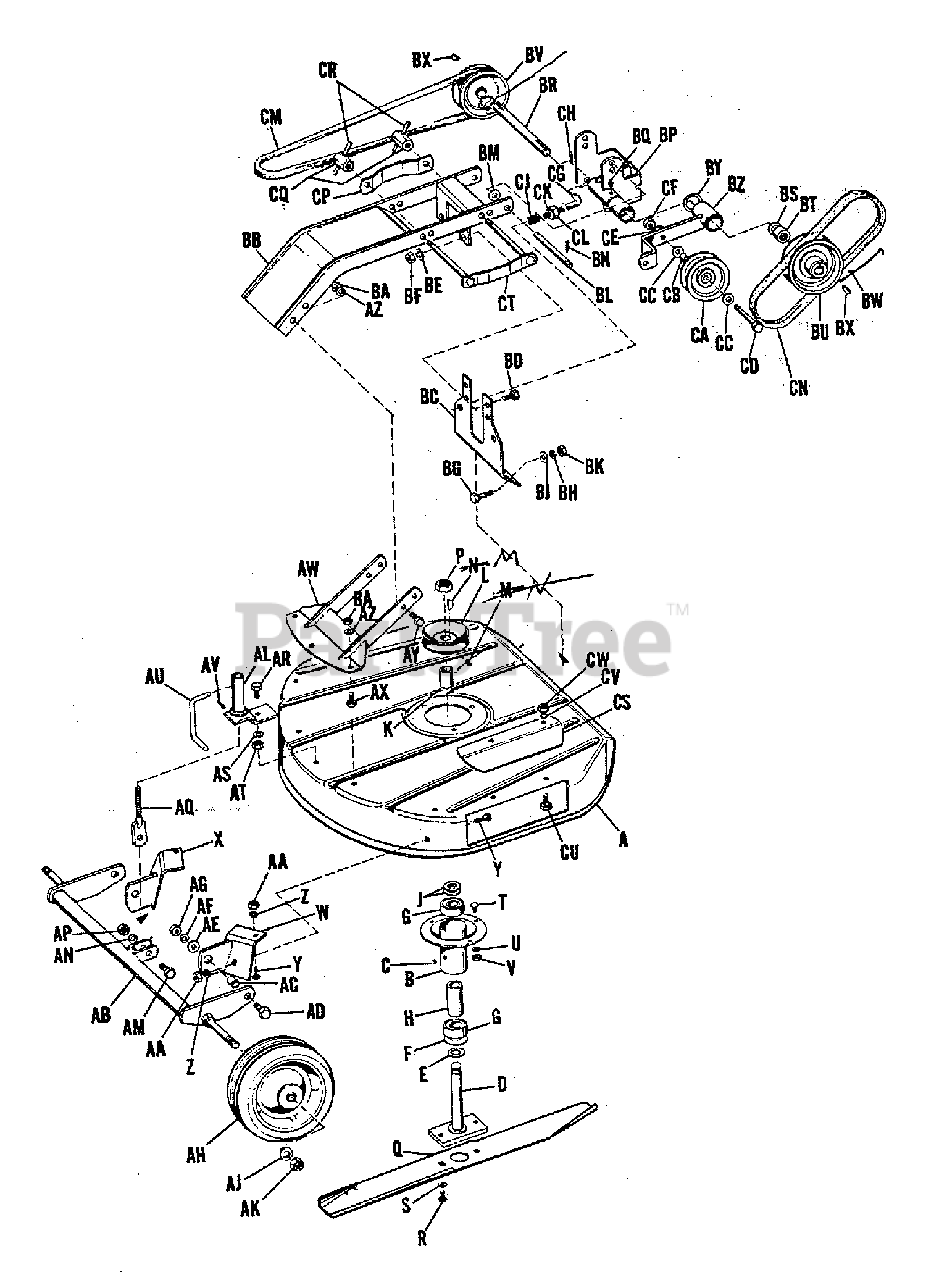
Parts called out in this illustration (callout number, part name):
B	ARBOR TUBE ASSEMBLY
C	PLUG, Pipe, 1/8" Standard
D	ARBOR ASSEMBLY
G	BEARING, Radial
M	KEY, Woodruff
N	SCREW, Set, Socket Head, Cup Point, 5/16-18 NC x 3/8" Lg.
P	NUT, Hex, Full Lock, 3/4"-16 NF
Q	BLADE, Knife
R	CAPSCREW, Hex, 3/8"-16 x 3/4" Lg.
S	LOCKWASHER, 3/8"
T	CAPSCREW, Hex, 3/8"-16 x 3/4" Lg.
U	LOCKWASHER, 3/8"
V	NUT, Hex, Full, 3/8"-16 NC
W	BRACKET ASSEMBLY, Front, R.H.
X	BRACKET ASSEMBLY, Front, L.H.
Y	CARRIAGE BOLT, 3/8-16 NC x 3/4" Lg.
Z	LOCKWASHER, 3/8"
AA	NUT, Hex, Full, 3/8-16 NC
AB	FRONT AXLE ASSEMBLY
AD	CAPSCREW, Hex, 3/8"-16 NC x 1" Lg.
AE	WASHER, Plain, 3/8" Standard
AF	LOCKWASHER, 3/8"
AG	NUT, Hex, Full, 3/8"-16 NC
AH	WHEEL ASSEMBLY
AJ	LOCKWASHER, 1/2"
AK	NUT, Hex, Full, 1/2"-13 NC
AL	BRACKET ASSEMBLY, Crank
AM	CAPSCREW, Hex, 3/8"-16 NC x 7/8" Lg.
AN	LOCKWASHER, 3/8"
AQ	SCREW ASSEMBLY, Height Adjusting
AR	CAPSCREW, Hex, 3/8"-16 NC x 1-1/4
AS	LOCKWASHER, 3/8"
AT	NUT, Hex, Full, 3/8"-16 NC
AU	CRANK, Height Adjusting
AV	PIN, Cotter, 3/32" x 3/4" Lg.
AW	SUPPORT ASSEMBLY, Front
AX	CAPSCREW, Hex, 3/8"-16 NC x 3/4" Lg.
AY	CAPSCREW, Hex, 3/8"-16 NC x 1" Lg.
AZ	WASHER, Lock, 3/8"
BA	NUT, Hex, Full, 3/8"-16 NC
BB	ARM ASSEMBLY, Push
BC	REAR BRACKET
BD	CAPSCREW, Hex, 3/8"-16 NC x 3/4" Lg.
BE	LOCKWASHER, 3/8"
BF	NUT, Hex, Full, 3/8"-16 NC
BG	CAPSCREW, Hex, 5/16"-18 NC x 3/4" Lg.
BH	LOCKWASHER, 5/16"
BJ	WASHER, Plain, 5/16"
BK	NUT, Hex, Full, 5/16"-18 NC
BL	PIN, Pivot
BM	WASHER, Plain, 3/8"
BN	PIN, Cotter, 3/32" x 7/8" Lg.
BP	BRACKET ASSEMBLY, Drive
BQ	FITTING, Grease, #1641 Alemite
BR	SHAFT, Idler
BT	BEARING, Needle
BW	SCREW, Set, Hollow Head, Cup Point, 5/16-18 NC x 1/2" Lg.
BX	KEY, Woodruff, #9
BY	RING, Retaining
BZ	LEVER ASSEMBLY, Idler
CA	PULLEY, Idler
CC	WASHER, Plain, 5/16"
CD	CAPSCREW, Hex, 3/8"-16 NC x 1-3/4"
CE	WASHER, Lock, 3/8"
CF	NUT, Hex, Full, 3/8"-16 NC
CH	PIN, Cotter, 3/32" x 7/8" Lg.
CK	WASHER, Plain, 5/16"
CL	NUT, Hex, Jam, 3/8"-16 NC
CM	BELT, "V" (Cross Drive)
CN	BELT, "V" (Drive)
CP	PLATE, Hitch, Side
CQ	NUT, Body
CR	HANDLE, "T"
CS	DEFLECTOR
CT	CLAMP ASSEMBLY, Hitch
CU	CAPSCREW, Hex, 1/4"-20 NC x 1/2" Lg.
CV	LOCKWASHER, 1/4"
CW	NUT, Hex, Full, 1/4"-20 NC
